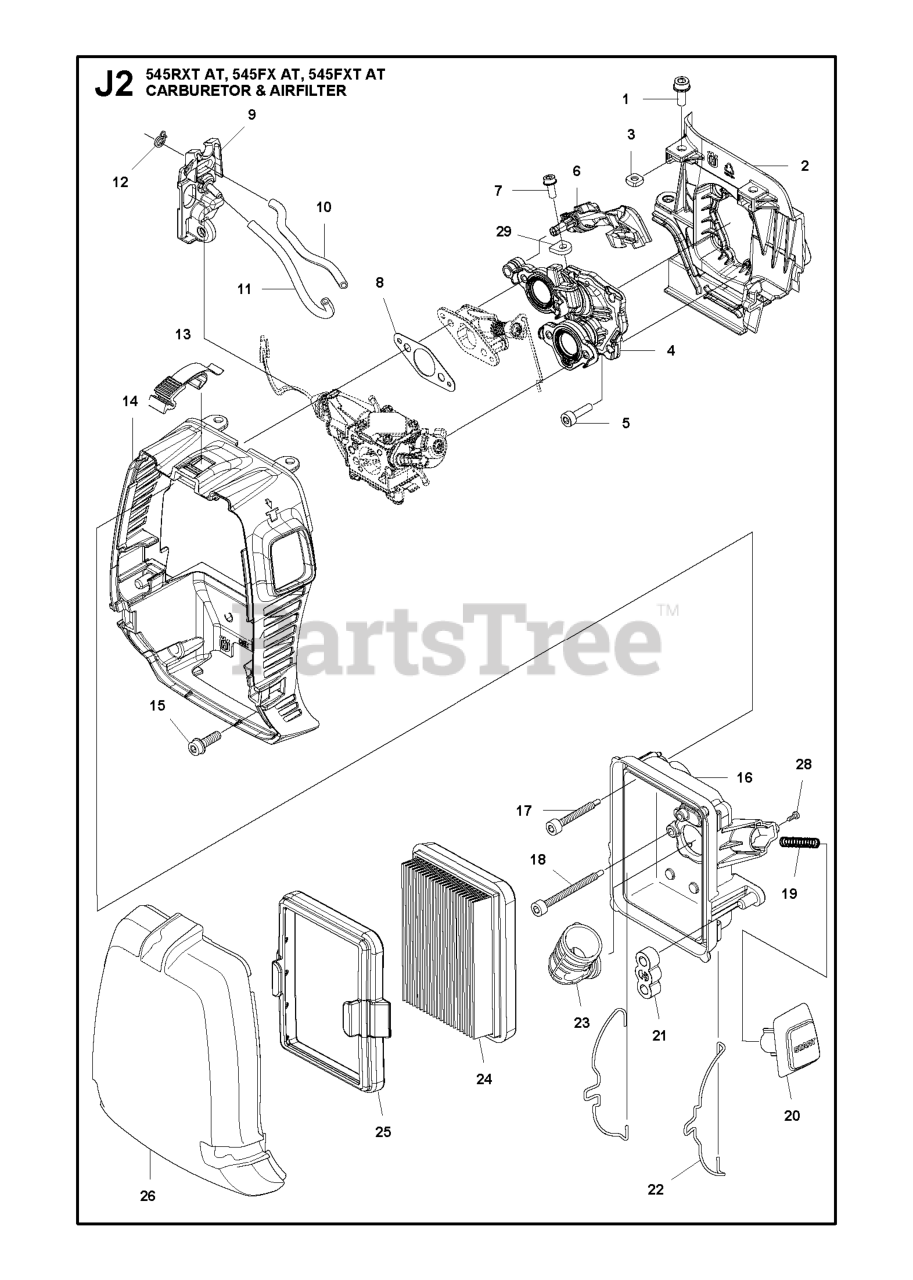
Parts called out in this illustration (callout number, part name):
2	INSULATION WALL ASSY
6	WIRE HOLDER THROTTLE WIRE
7	SCREW IHSCM M5X20 8.8 TBO
9	GROMMET ASSY
10	FUEL HOSE/127MM
11	FUEL HOSE STRAIGHT 110
12	HOSE CLAMP
14	FRAME ASSY HUSQVARNA
15	SCREW IHSCFM
16	HOLDER INLET
17	SCREW IHSCM M4X35 12.9 TBO DO
18	SCREW IHSCM M4X50 12.9 TBO DO
19	SPRING START BUTTON SPRING
20	START BUTTON ASSY.
21	SUPPORT RUBBER
23	AIR INTAKE CARBURETTOR
24	AIR FILTER
25	FRAME FILTER FIXATION
26	PROTECTIVE COVER INLET GREY, H
29	LOCKING NUT M6
